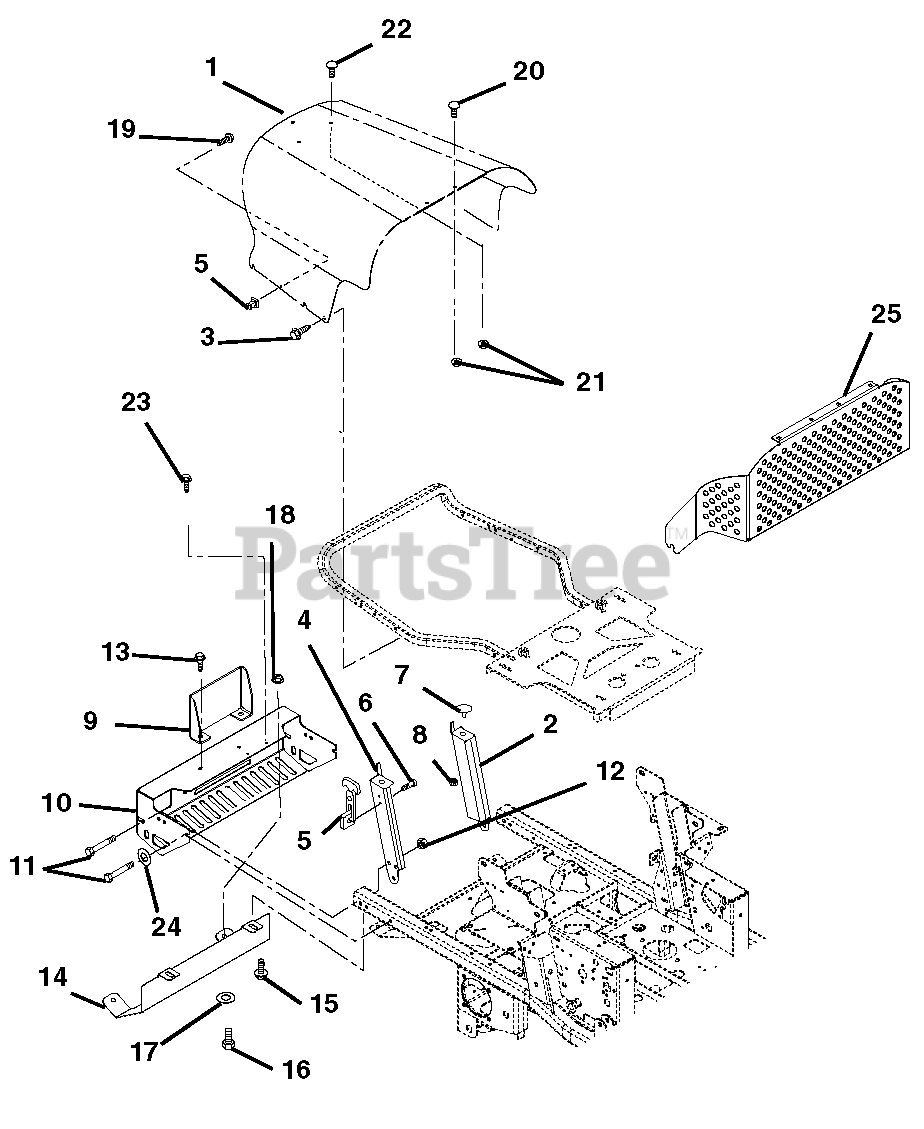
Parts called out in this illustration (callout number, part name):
2	Weldment, Hood Support, Left Hand
3	Screw, Tapping .38-16 x .75 Hex Washer Head
4	Weldment, Hood Support Right Hand
5	Latch, Rubber
6	Screw, Machine 10-24 x .50 Hex Washer Head
7	Button Bumper
8	Nut, Spin Lock Flange .312-18
9	Guard, Muffler
10	Bumper, Rear
11	Bolt, Hex .38-16 x 2.75 Grade 5
12	Nut, Locking Top Flange .38-16
13	Screw, Tapping .38-16 x .75 Hex Washer Head
14	Heat Shield
15	Screw, Tapping .38-16 x .50 Hex Washer Head Thread Rolling YWZ
16	Bolt, Hex .38-16 x .75 Grade 5
17	Washer, Flat Steel .438 x1.00 x .083 YWZ
18	Nut, Locking Top Flange .38-16
19	Screw, Machine 10-24 x 1.50 Hex Washer Head
20	Bolt, Round Head Square Neck .25-20 x .50 Grade 5
21	Nut, Locking Top Flange .25-20
22	Bolt, Round Head Square Neck .25-20 x .75 Grade 5
23	Screw, Tapping .25-20 x .50 Hex Washer Head Thread
24	Washer, Flat Steel .406 x .812 x .065
25	Plenum, Hood
